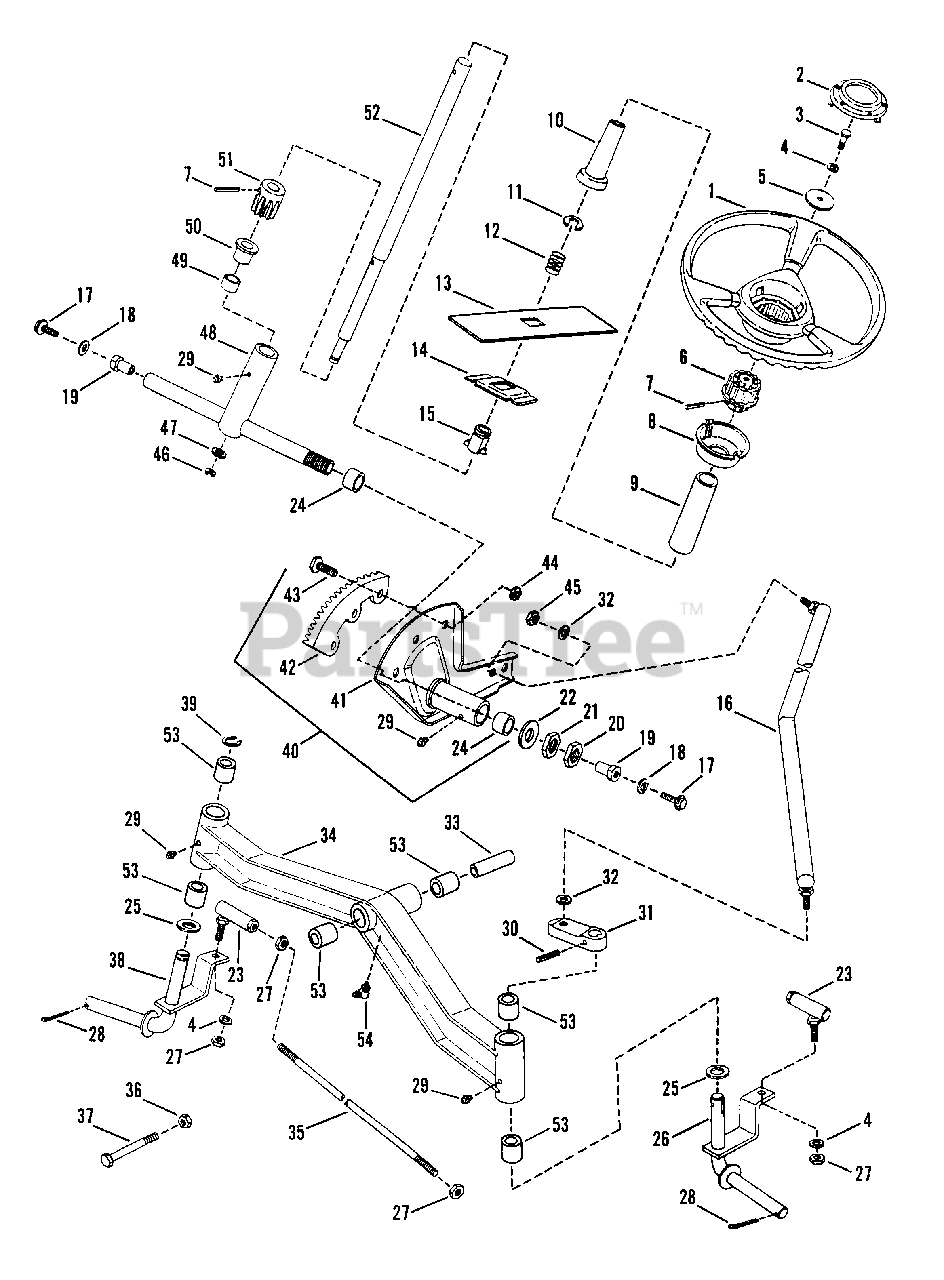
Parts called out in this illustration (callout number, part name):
1	STEERING WHEEL
2	CAP, Steering Wheel
3	BOLT, 3/8-16 x 7/8"
4	WASHER, 3/8 Split Lock
5	WASHER, Flat
6	ADAPTER, Steering Wheel
7	ROLL-PIN, 1/4 x 1 1/4"
8	BASE, Steering Wheel
9	COVER, Foam
10	ACTUATOR, Steering Lock
11	RING, Retaining
12	SPRING, Actuator
13	COVER, Slide
14	RISER, Steering Lock
15	BUSHING, Steering Lock
16	DRAG-LINK
17	SCREW, 5/16-18 x 3/4" Self-Tapping
18	WASHER, 5/16 Internal Tooth Lock
19	PIVOT
20	NUT, 3/4-16 Hex Jam
21	NUT, 3/4-16 Hex
22	WASHER, 3/4 SAE Flat
23	BALL JOINT, 3/8-24 Thread
24	BEARING, Sleeve, .750" Long
25	WASHER, Thrust
26	KING-PIN, Left Side
27	NUT, 3/8-24 Hex
28	COTTER-PIN, 5/32 x 1"
29	LUBE FITTING, Straight (press-fit for .187 dia. Hole)
30	ROLL-PIN, 1/4 x 1 1/4"
31	ARM, Steering
32	WASHER, 1/2 Split Lock
33	JOURNAL, Axle
34	ASSEMBLY, Front Axle
35	TIE-ROD
36	NUT, 1/2-20 Hex Lock
37	SCREW, 1/2-20 x 4" Hex Head Cap
38	KING-PIN, Right Side
39	RING, Retaining
40	ASSEMBLY, Steering Sector
41	WELDMENT, Steering Sector
42	GEAR, Steering Sector
43	SCREW, 1/4-20 x 5/8" Hex Head Cap
44	NUT, 1/4-20 Hex Center Lock
45	NUT, 1/2-20 Hex
46	RING, Retaining
47	WASHER, 3/8" Flat
48	ASSEMBLY, Bearing Support
49	BUSHING
50	FLANGE
51	PINION, Steering
52	SHAFT, Steering
53	BEARING, Sleeve, 1.00" Long
54	FITTING, Lube
